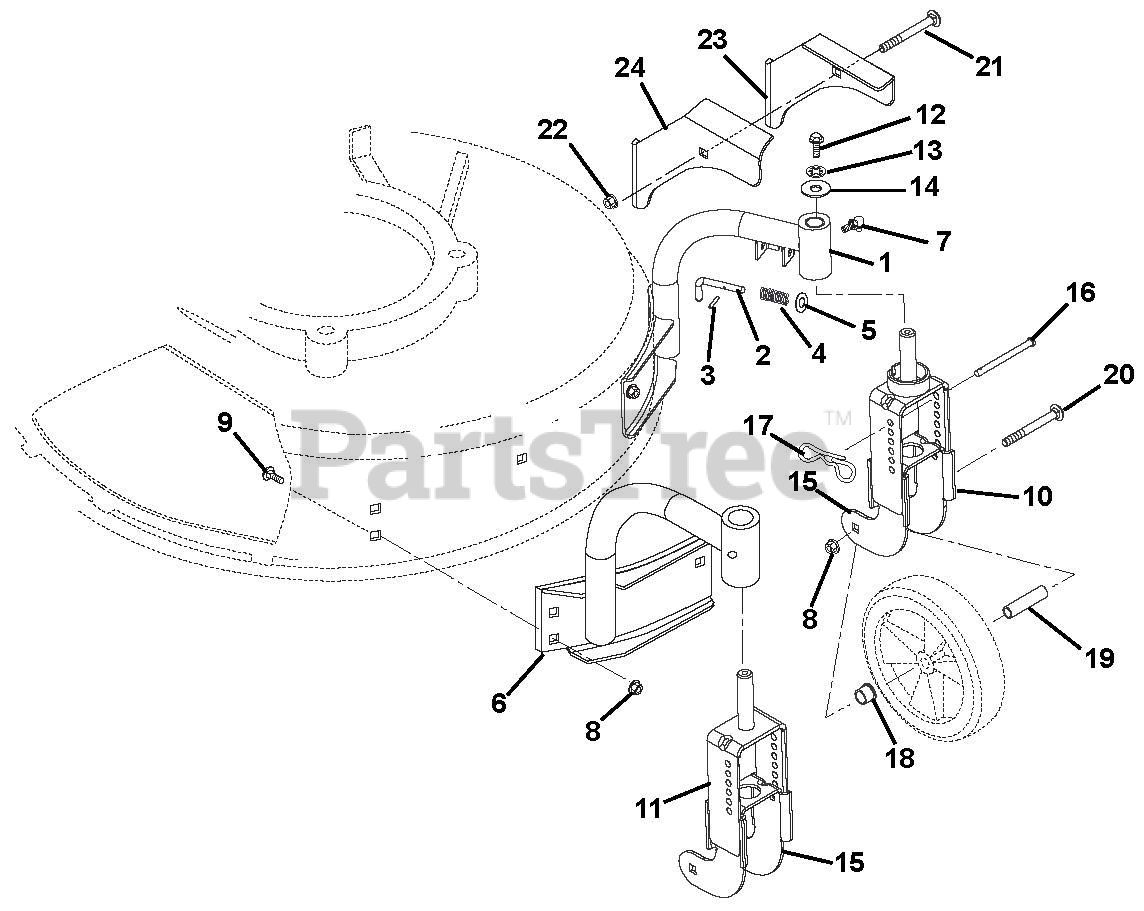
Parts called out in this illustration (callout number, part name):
1	ASSY, MOUNT LH W/BUSHINGS
2	PIN, LOCKOUT
3	PIN-ROLL .094X.750
4	SPRG, COMP--SWVL LOCKOUT
5	@WSHR-FL-STL.281X.62X.065 YWZC
6	ASSY, RH MOUNT W/BUSHINGS
7	FTG-LUBE .25-28X.256 YWZC
8	@NUT-SPNLK-FLG .312-18 YWZC
9	@BLT-RDHDSQNK .31-18X.50 G5YZ
10	YOKE, OUTER LH
11	YOKE, RH OUTER
12	@BLT-HEX .25-20X.75 GR5 YWZC
13	@WSHR-LK .25X.062 REG YWZC
14	WSHR-FL-STL .281X1.000X.063
15	YOKE-INNER
16	PIN, HEIGHT ADJUSTMENT
17	PIN, BOW TIE LOCKING COTTER
18	BSHG-FLG .500X.625X.500X.750
19	SPCR, WHEEL .385X.500X2.00
20	BLT-RDHDSQSHNK.31-18X2.75G2YWZ
21	@BLT-RDHDSQNK .25-20X1.50 G5YZ
22	@NUT-SPNLK-FLG .25-20 YWZC
23	BRACKET, HOOD CABLE--LH
24	BRACKET, HOOD CABLE WELDMENT
